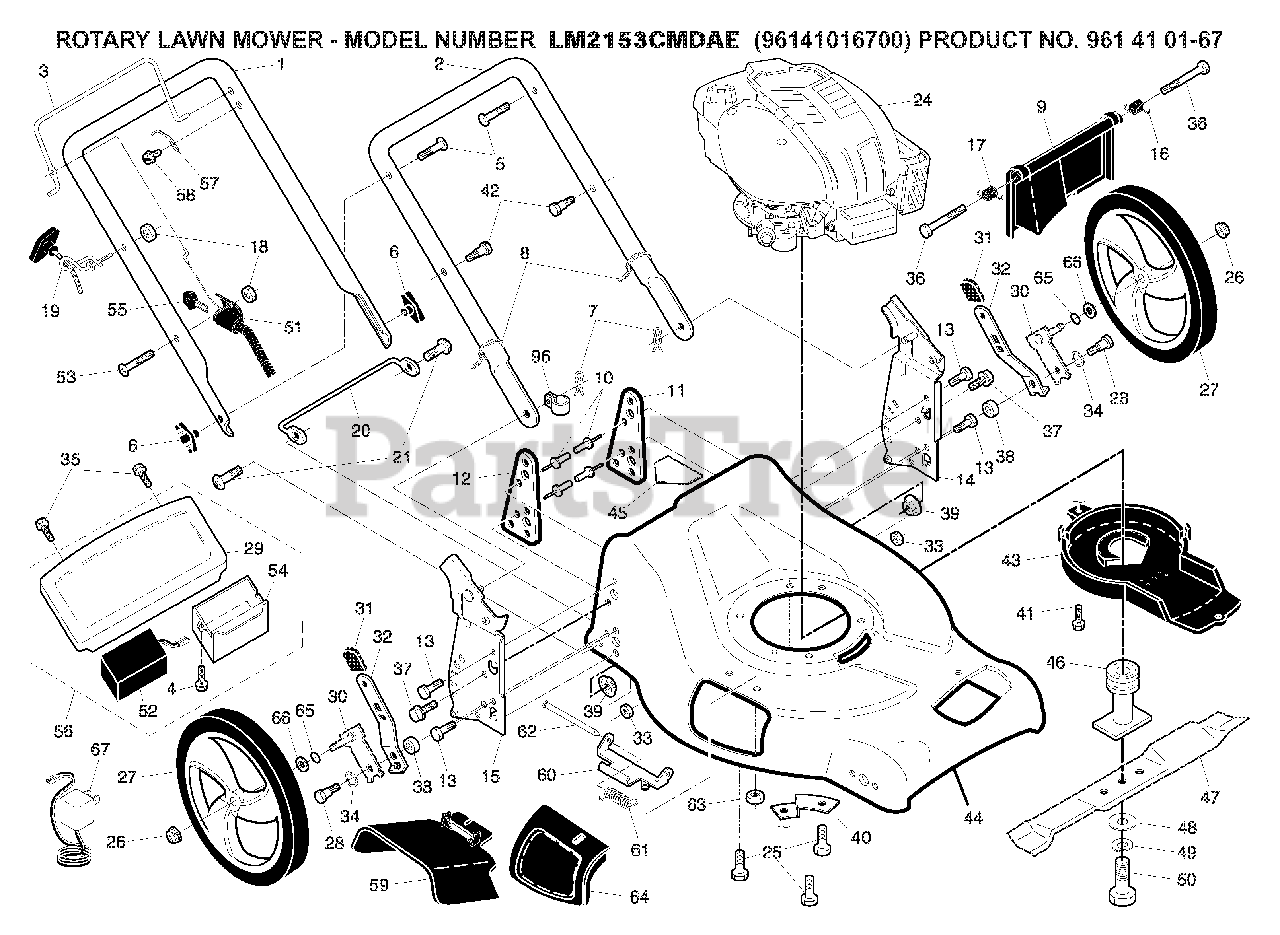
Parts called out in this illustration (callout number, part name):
1	HANDLE.UPER.D.ST.EZ
5	BOLT, HANDLE 5/16-18X1.75
6	KNOB, DEFLECTOR
7	HAIRPIN COTTER
8	TIE GUIDE
9	REAR DOOR ASSEMBLY
10	RIVET BLIND
11	SUPPORT BRACKET LH
12	SUPPORT BRACKET RH
13	SCREW 14-20 X 5/8
14	BRKT.ASM.HNDL.21FGD.EZ
15	BRKT.ASM.HNDL.21FGD
16	SPRING.REAR.DOOR.EZ.21.LT
17	SPRING.REAR.DOOR.EZ.21.RT
18	NUT
19	GUIDE.ROPE.STD.BLK.ZIN
21	SCREW
25	BOLT 3/8-16X1-1/8
26	NUT.HEX.FLANGE.3/8-16.LOCKNUT
28	SHOULDER BOLT 5/16-18
29	PANEL.TRIM.21.FWGD.ES
30	ARM.ASM.AXLE.REAR.5/9.POS.BZP
31	SELECTOR KNOB
32	SELECTOR SPRING
33	NUT.71038.31-18.HEX.NYLOCK
34	WASHER FLAT
35	SCREW.PAN.HEAD.#10
38	SPACER.HEIGHT.ADJUSTER
39	NUT.FLANGE.5/16
40	BRACKET
41	SCREW.HEX.WSH
42	SCREW.SHOULDER.HH.10X.281X.6
43	DEBRIS SHIELD
45	DECAL.INTERNATIONL.CUTFINGER
47	BLADE.21.PUSH
48	WASHER,HARDEN
49	LOCKWASHER
50	SCREW, HEX HD 3/8-24 X 1-3/8
51	KEY.START.CONTROL.W/ZONE
52	BATTERY.AMP.CONNECTOR
53	SCREW.(COMBINATION CONTROL)
54	BOX.BATTERY.TRIM
55	KEY.MOLDED
56	PANEL.ASM.TRIM/BATTERY.BOX
57	BRACKET UPSTOP
59	DISCHARGE DEFLECTOR
60	HINGE BRACKET ASSEMBLY
61	SPRING.TORSION
62	ROD.HINGE.21
63	LOCKNUT
64	DOOR.MULCH.21.REAR
65	O-RING..070X.487.NEOPRENE
66	WASHER PM
96	CLIP.CABLE.BLK
